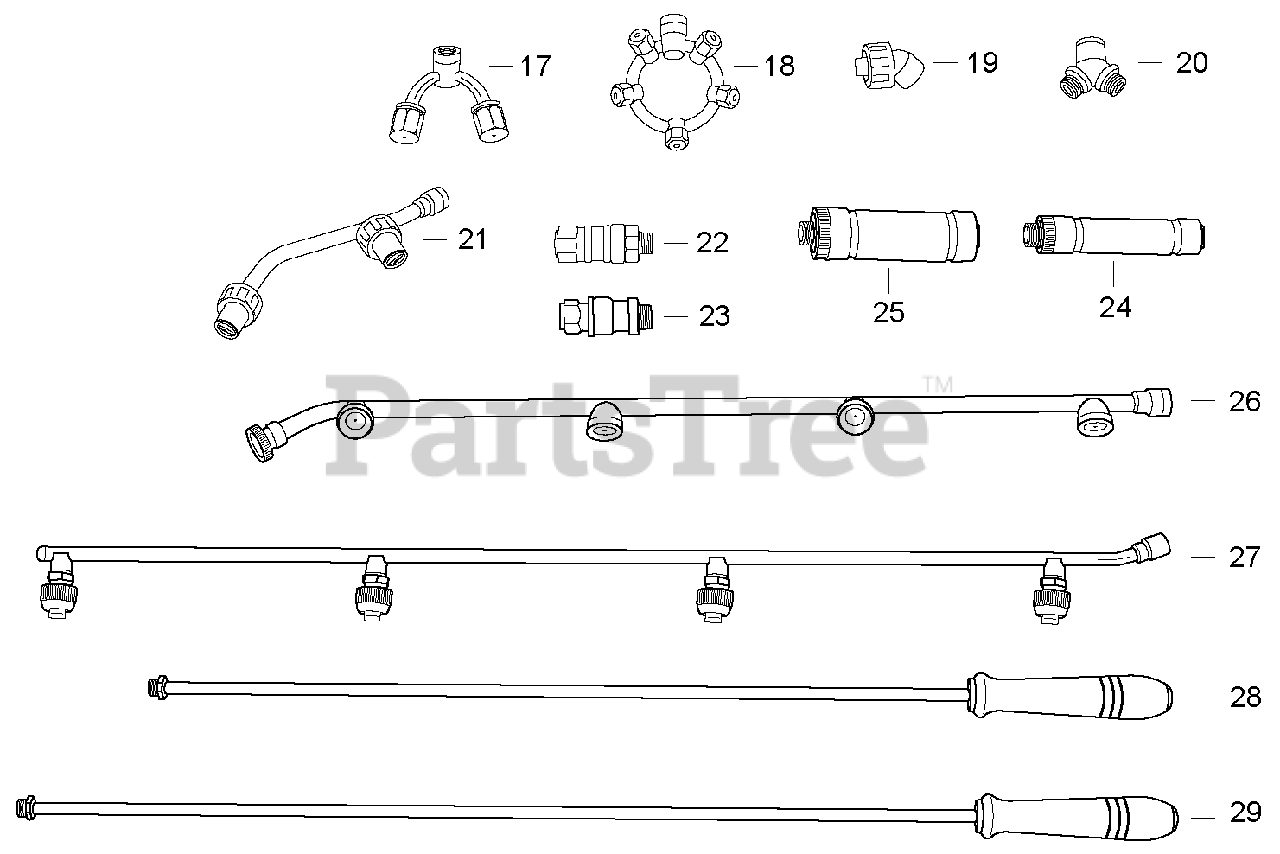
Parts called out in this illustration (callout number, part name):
17	NOZZLE ASSY
18	NOZZLE ASSY
19	NOZZLE ASSY
20	ADAPTOR
21	NOZZLE ASSY
22	CONNECTOR, SWIVEL
23	SWIVEL
24	FILTER, FLUID
25	FILTER, FLUID - HEAVY DUTY
26	SPRAY WAND ASSY
27	SPRAY WAND ASSY
28	WAND, SPRAY - 680mm
29	WAND, SPRAY - 890mm
